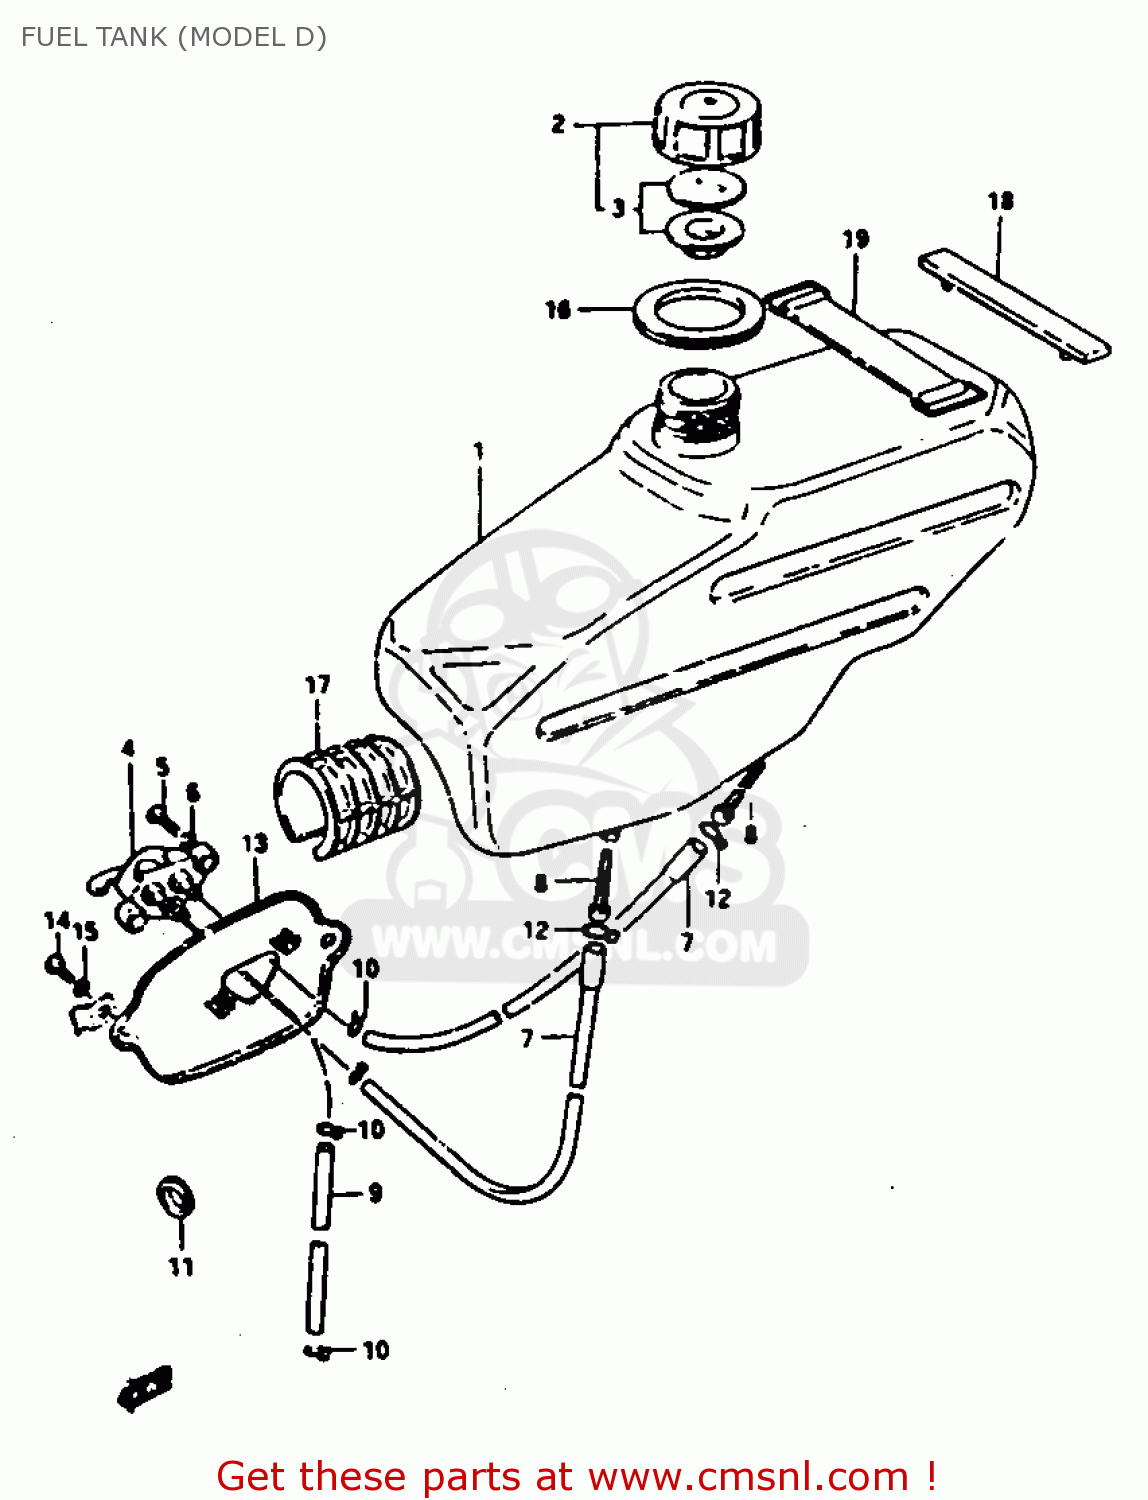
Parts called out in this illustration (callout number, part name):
1	TANK, FUEL
2	CAP SET,FUEL TANK FILLER
3	GASKET,OIL TANK CAP (NAS)
4	COCK ASSY,FUEL
5	SCREW
6	LOCK WASHER
7	HOSE,FUEL
8	FILTER,FUEL
9	HOSE,FUEL
10	CLIP
11	GROMMET
12	CLIP
13	PLATE, FUEL COCK (RED)
14	SCREW(5X12)
15	LOCK WASHER
16	CUSHION, TANK UPPER
17	CUSHION,FUEL TANK
18	CUSHION, TANK REAR
19	BAND
